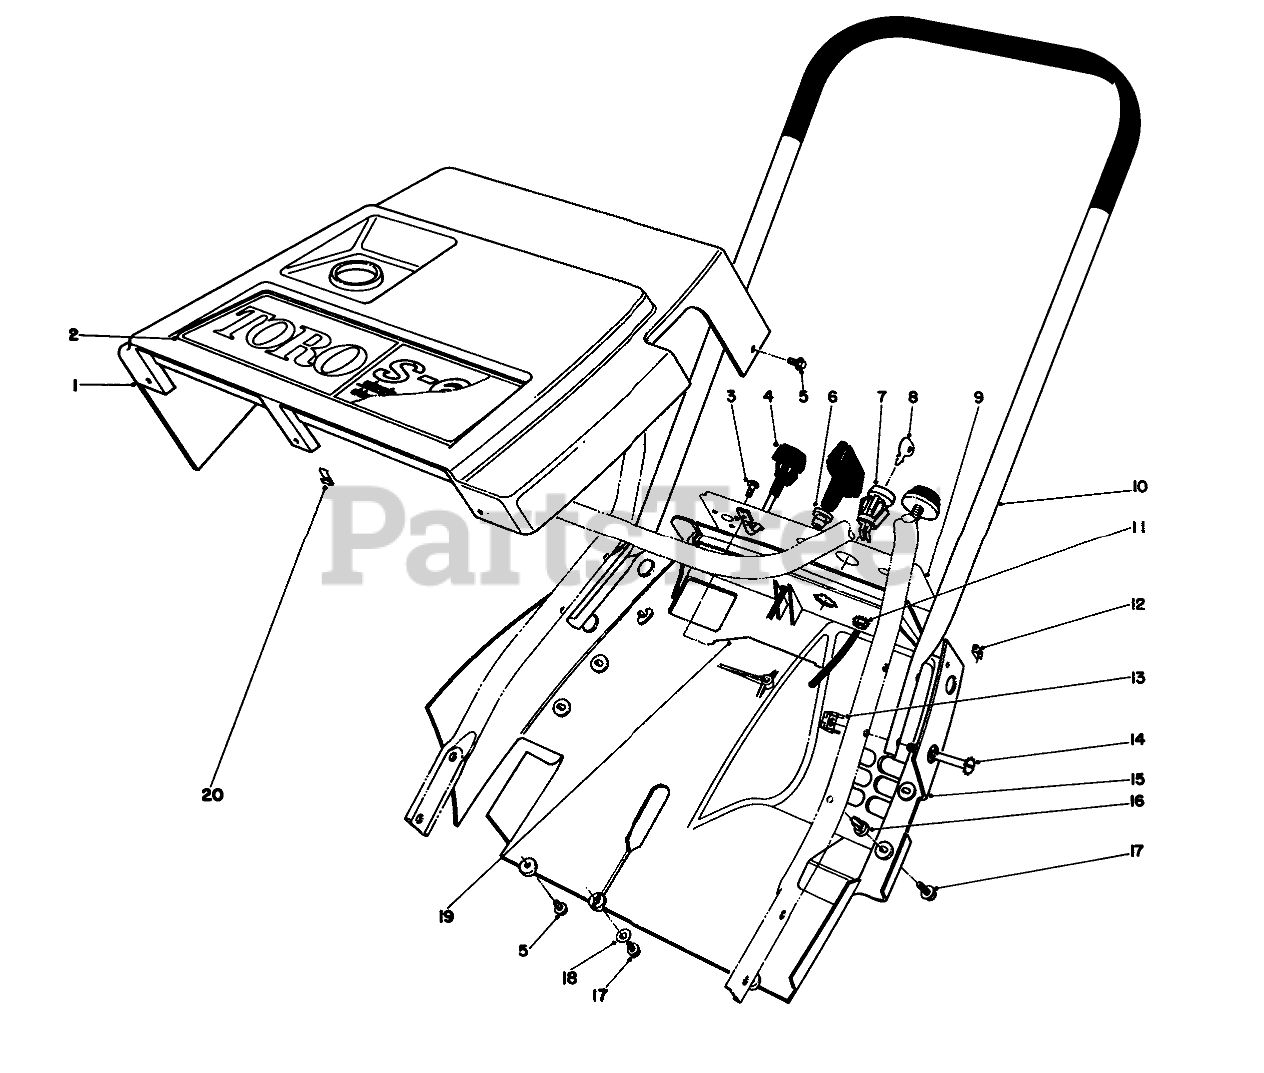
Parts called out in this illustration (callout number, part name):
1	Shroud-Upper
2	TORO DECAL
3	SCREW-PLASTITE
4	CHOKE CONTROL ASM
5	Screw
6	GUIDE-ROPE, STARTER
7	SWITCH
8	Key
9	Decal-Control Panel
10	Handle-Upper
11	NUT-KEPS
13	TINNERMAN NUT
14	SCREW-HEX HD SLOT
15	LOWER SHROUD
16	Nut-Push
17	Self Tapping Screw
18	WASHER-FLAT
19	CONTROL WIRE
20	NUT "U"
